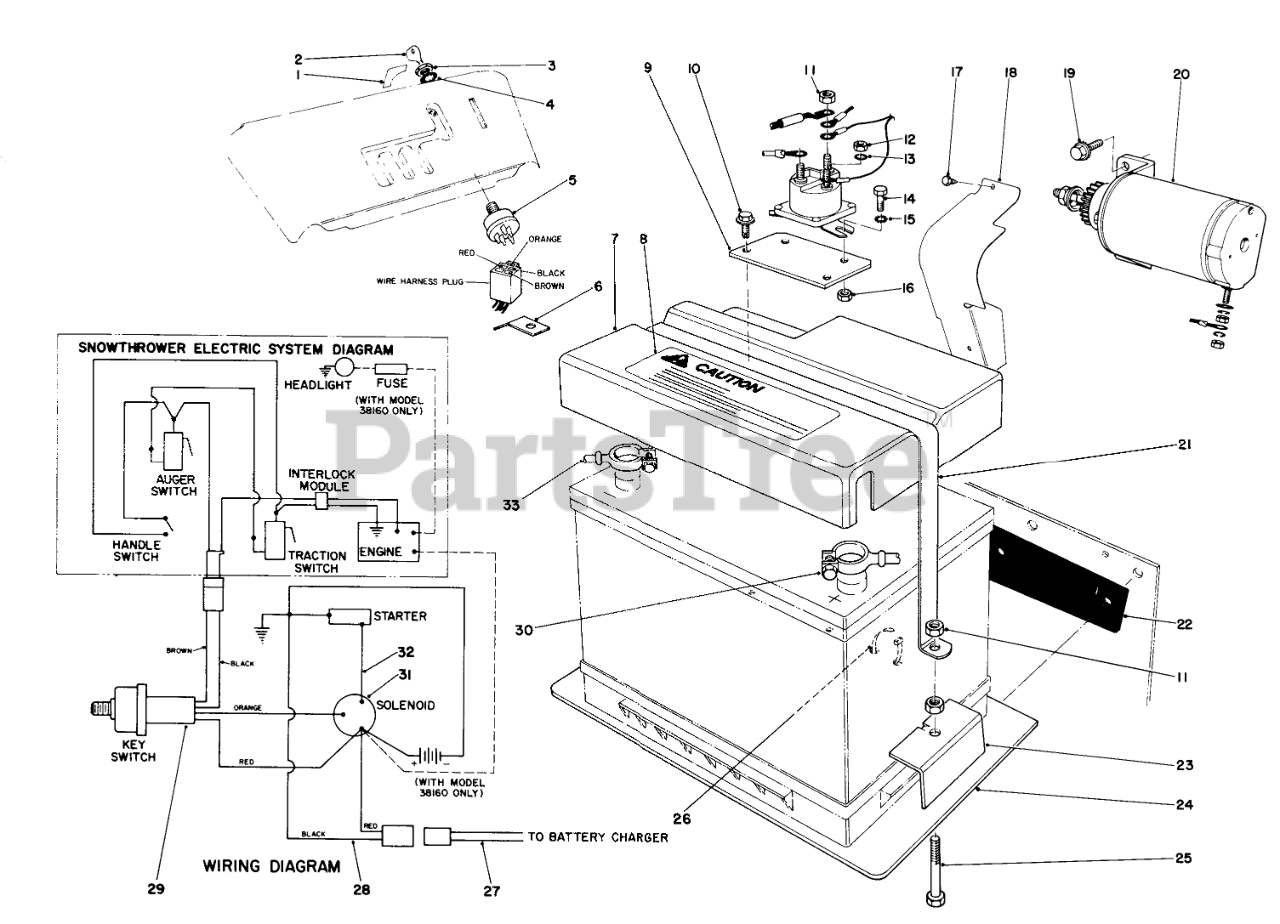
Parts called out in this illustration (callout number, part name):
1	Decal Switch
2	Key
3	NUT-HH
4	WASHER-TOOTH, INTERNAL
5	Starter Switch (Incl. Ref. #3 & 4)
6	Bracken Wire Clamp
7	Battery Cover (Incl. Ref. #8)
8	0630 Decal-Caution
9	Bracket Solenoid
10	SCREW-HWH
11	NUT-HEX
12	NUT-HEX
13	WASHER-LOCK, INT
14	SCREW-HH
15	WASHER-LOCK/EXT
16	NUT-LOCK, NI
17	Hex Hd. Sems Screw
18	Pinion Shield
19	Screw-HH
20	Starter Motor & Pinion Assy.
21	Strap Battery
22	Batery Isolation Pad
23	BATTERY CLAMP
24	Battery Mounting Plate
25	SCREW-HH
26	TIE-CABLE
27	MALE WIRE ASM
28	FEMALE WIRE ASM
29	Wire Harness
30	BATT-SOLENOID CABLE
31	SOLENOID
32	STRT MTR-SOLNOID WIRE
33	BATT-GROUND CABLE
